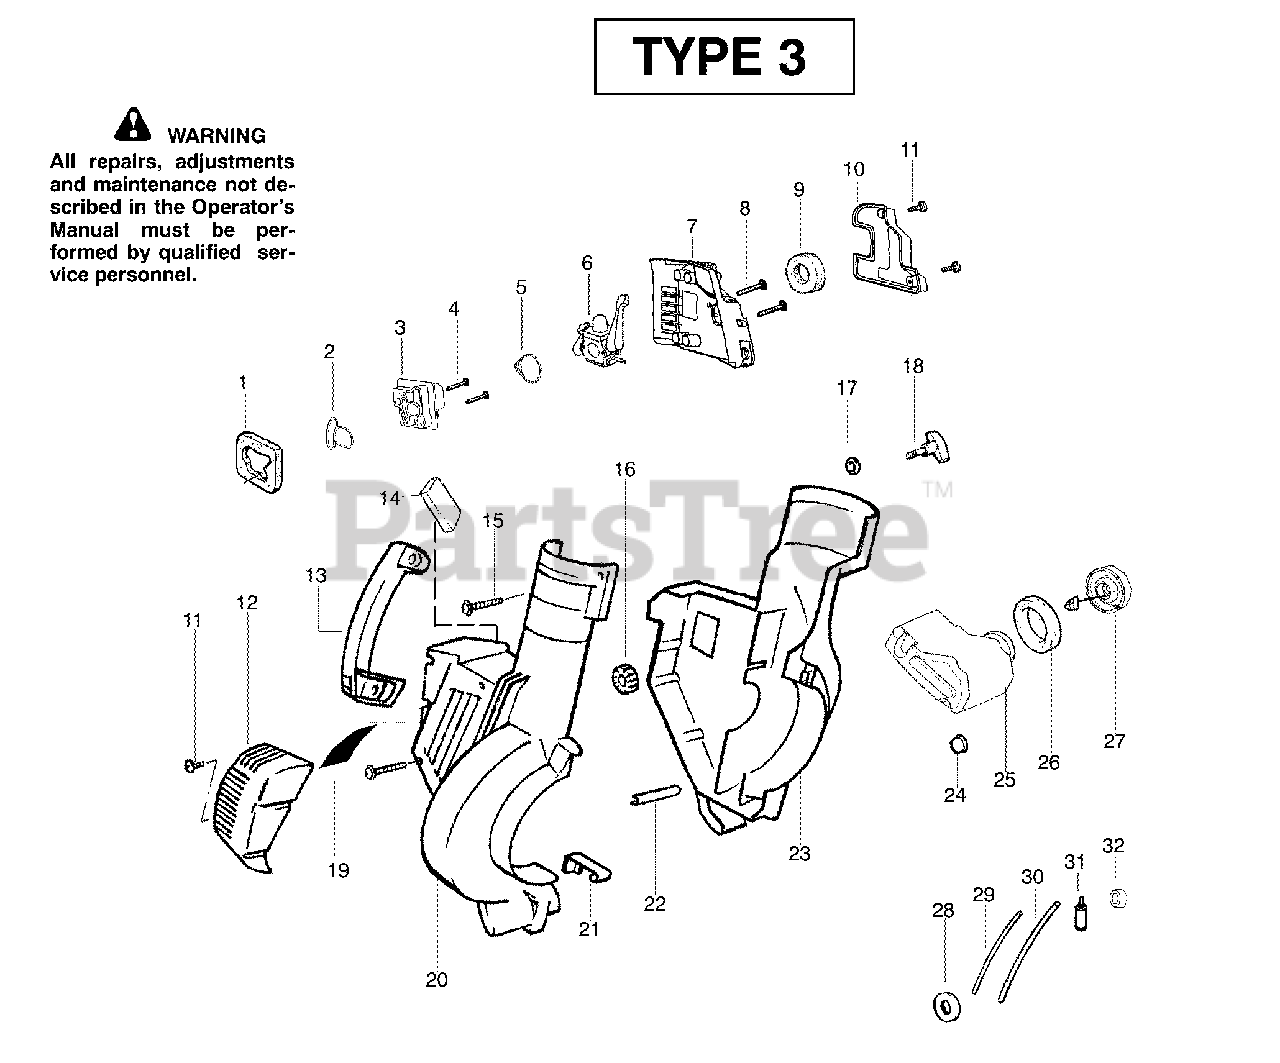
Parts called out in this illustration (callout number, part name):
1	Air Dam (Kit)
2	Gasket-Adapter (Kit)
3	Carburetor Adaptor
5	Gasket-Carburetor (Kit)
6	Kit-Carb Ass'y. (C1Q-W11)
6	Kit-Carb Ass'y. (C1Q-W11C)
8	Screw-Carb.
9	Filter-Air
10	Cover-Air Filter
12	Guard-Muffler
14	Foam - 71.12mm (Kit)
16	Isolator
18	Knob-Tube Clamp
19	Reflector-Heat (Kit)
20	Assy-Housing-Right
21	Spring-Cover Latch
22	Guide-Starter Rope
23	Housing-Left
24	Isolator-Crankcase
25	Assy-Fuel Tank
26	Gasket-Fuel Tank
27	Fuel Cap w/Retainer
28	Grommet-Shroud
29	Kit-Line Carb/Purge
30	Kit-Line Tank/Purge
31	Assy-Fuel Pick-up
32	Grommet-Fuel line (Kit)
